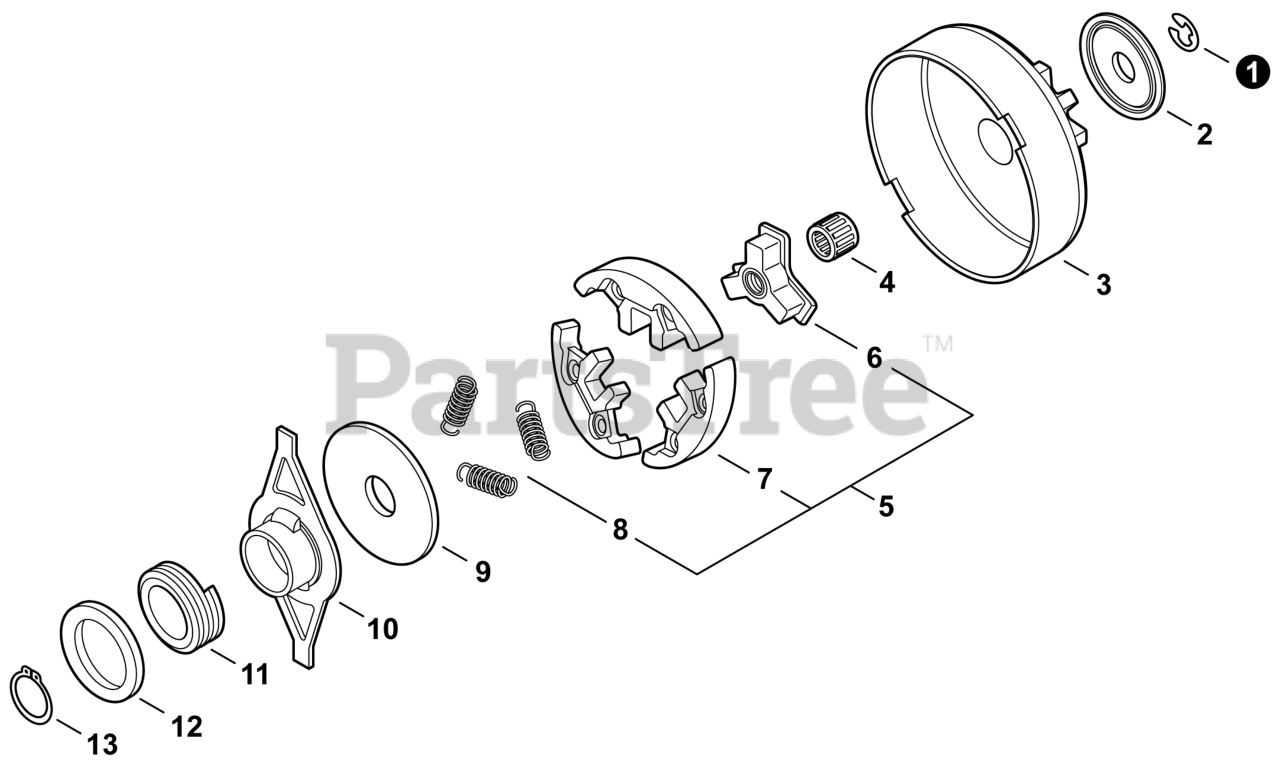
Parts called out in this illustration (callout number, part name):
1	E-RING 8.1
2	WASHER 10
3	DRUM, CLUTCH
4	BEARING, NEEDLE 10
5	CLUTCH ASSY
6	HUB, CLUTCH
7	CLUTCH SHOE SET (3PCS)
8	SPRING, TENSION
9	PLATE, CLUTCH
10	COLLAR 15x19x73
11	GEAR, WORM
12	WASHER 15.5x22.5x0.5
13	RING, RETAINING 15
